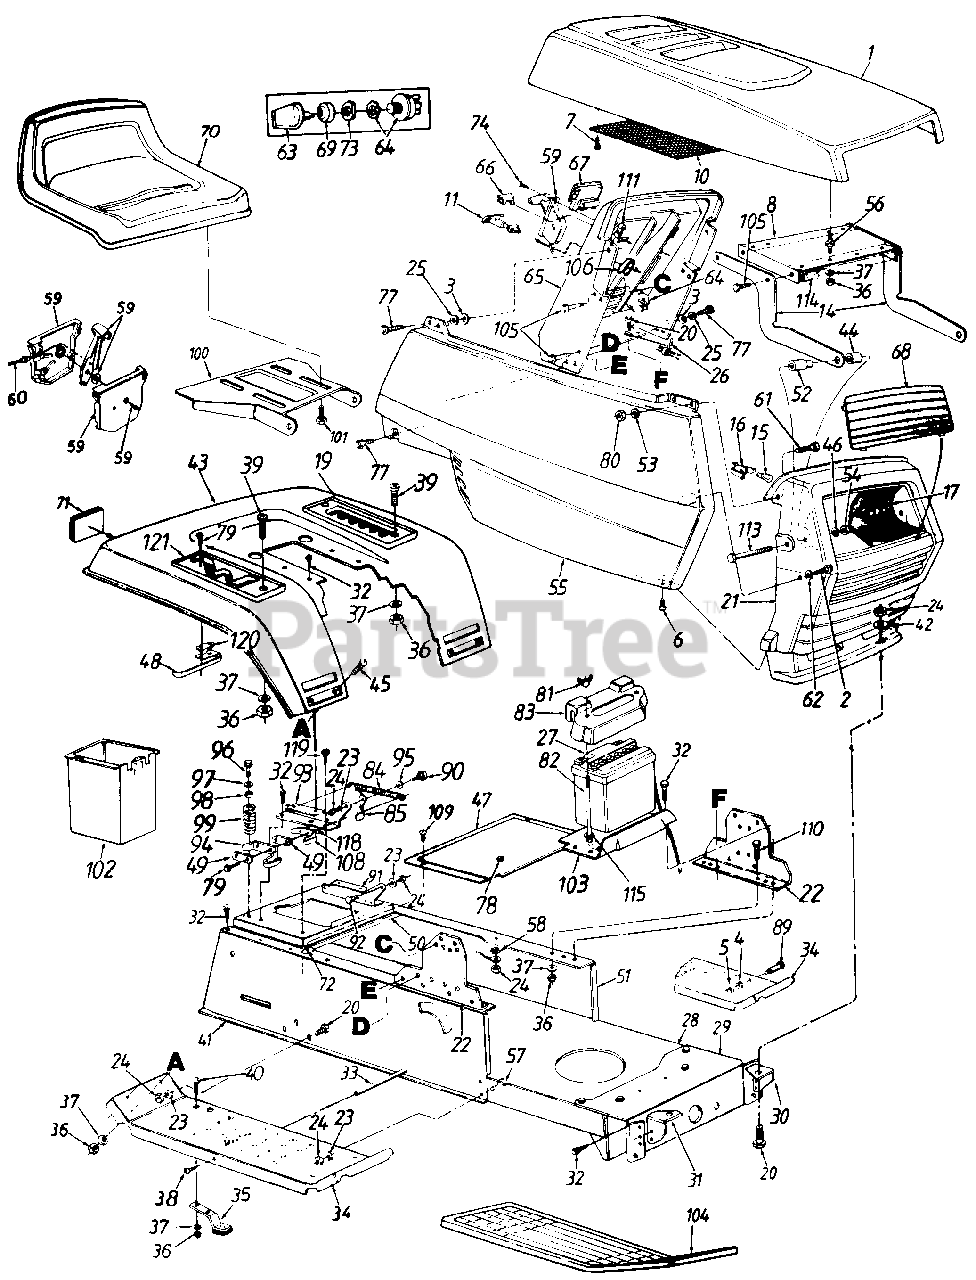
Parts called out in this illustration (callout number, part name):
3	Bolt Retainer 1/4" I.D.
4	L-Wash. 3/8" I.D.
5	Hex Nut 3/8-16 Thd.
6	Truss Mach. AB-Tap Scr. #10 x .5" Lg.
7	Hex Wash Hd. AB-Tap Scr. #8 x .5" Lg.
8	Hood Plate
11	Choke Control 46" Lg.
14	Hood Hinge
15	Lamp
16	Twist Lock-Lamp Socket
17	Reflector-Headlight
19	7 Speed Index Brkt.
20	Hex Bolt 5/16-18 x .75" Lg.
21	Grille
22	Dash Support Bracket
23	L-Wash. 5/16" I.D.
24	Hex Nut 5/16-18 Thd.
25	Fl-Wash. 1/4" I.D. x .93" O.D.
26	Cable Tie
27	12 Volt Battery
28	Lower Frame
29	Front Pivot Brkt.
30	Grille Mount Brkt.-L.H.
31	Grille Mount Brkt.-R.H.
32	Hex Wash. Hd. AB-Tap Scr. 5/16 x .75" Lg.
33	Running Board Rod
34	Running Board
35	Blade Brake Ass'y.
36	Hex Nut 1/4-20 Thd.
37	L-Wash. 1/4" I.D.
38	Truss Mach. Scr. 5/16-18 x .75"
39	Truss Mach. Scr. 1/4-20 x .75"
40	Carr. Bolt 1/4-20 x .62"
41	R.H. Side Frame
42	Fl-Wash. .34" I.D. x .68" O.D.
43	Rear Fender
44	Spacer .33" l.D. x .625" O.D.
45	Carriage Bolt 1/4-20 x .50" Lg.
46	Fl-Wash. .328" I.D. x .68" O.D.
47	Transmission Panel
48	Reverse Safety Switch
49	Insulator Plate
50	Hitch Plate
51	L.H. Side Frame
52	Shld. Spacer .33" l.D.
53	Fl-Wash. .281" I.D. x .5" O.D.
54	Hex Cent. L-Nut 5/16-18 Thd.
55	Side Cover-R.H.
56	Double Ended Stud 1/4-20 Thd.
57	Truss Hd. Scr. 5/16-18 x 1.0" Lg.
58	Ext. L-Wash. 5/16" I.D.
59	Throttle Control Box Ass'y.
60	Throttle Control Wire 18.5" Lg.
61	Hex Bolt 1/4-20 x .62" Lg.
62	Fl-Wash. .281" l.D. x .73" O.D.
64	Ignition Switch
66	Light Switch
67	Ammeter
68	Lens
69	Ignition Switch Cap
71	Reflector
72	Speed Nut #10Z
73	Ignition Switch Nut
74	Truss Mach. AB-Tap Scr. #10 x .5" Lg.
77	Hex Wash. Hd. Tap Scr. 1/4 x.75 Lg.
78	Snap Bushing
79	Hex Wash. Hd. AB-Tap Scr. #8 x .50" Lg.
80	Hex L-Nut 1/4-20 Thd.
81	Wing Nut 1/4-20 Thd.-Plastic
82	Battery Hold Down Rod
83	Battery Cover
84	Ext. Spring 5.31" Lg.
85	Seat Lift Brkt.
89	Shoulder Bolt
90	Shld. Bolt .437" Dia. x .268"
91	Seat Pivot Brkt. Support-L.H.
92	Shld. Bolt .437" Dia. x .162"
93	Seat Pivot Brkt. Support-R.H.
94	Spring Switch
95	Spr.-Wash. .445" I.D.
96	Hex Wash. Hd. Tap Scr. 5/16-18 x ln Lg.
97	Fl-Wash..344" I.D.
99	Compression Spring
100	Seat Pivot Bracket
101	Hex Tap Scr. 3/8-16 x .75"
103	Battery Bracket
104	Foot Pad-L.H.
105	Hex Tap Scr. 1/4-20 x .5" Lg.
106	Choke Retainer
108	Spring Switch
109	Truss Mach. Tap Scr. #10 x 5" Lg.
110	Hex Bolt 1/4-20 x .62" Lg.
111	Speed Nut 1/4-20 Thd.
113	Hex Bolt 5116-18 x 2.75" Lg.
115	Push Nut
118	Insulator Boss Plate
119	Truss Mach. Scr. 5116-18 x .75"
120	Insulator Nut Plate
121	Forward/Reverse Index Brkt.
